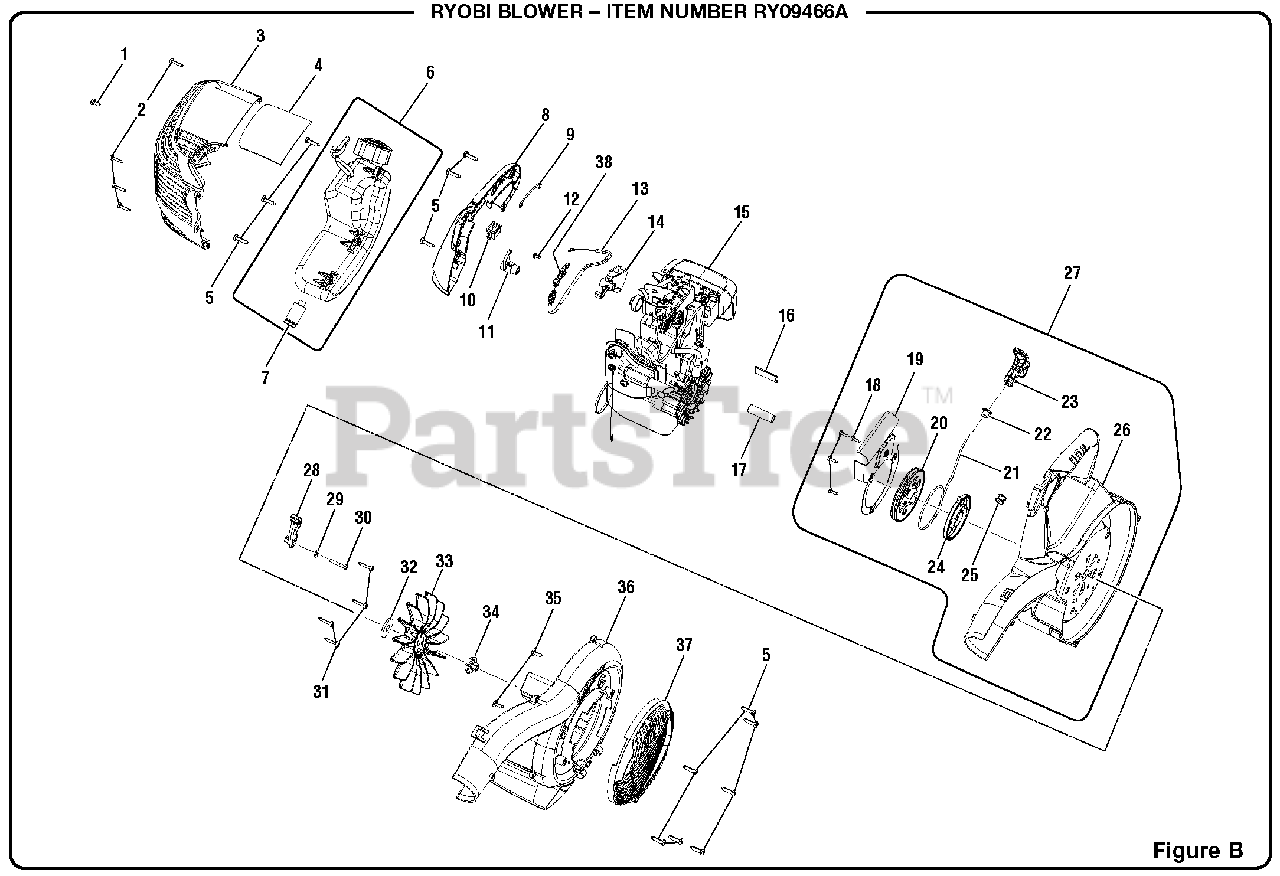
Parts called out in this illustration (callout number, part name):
1	Screw (M5 x 10.5 mm, T20 Torx Hd. )
2	Screw (M4 x 18 mm, T20 Torx Soc. Hd.)
3	Engine Housing
4	Heat Shield
5	Screw (#10-14 x 3/4 in, T25 Torx Pan Hd. T.F.)
6	Fuel Tank Assembly w/Cap
7	Fuel Filter
8	Handle Cover
9	Ground Wire
11	Trigger Lock
12	Screw (M3.5 x 7.5 mm, T20 Torx Pan Hd.)
13	Throttle Cable
15	Power Head Assembly
18	Screw (M4 x 12 mm, T20 Torx Truss Hd.)
20	Starter Pulley
21	Starter Rope
23	Starter Grip
24	Container Spring Assembly
26	Inner Volute
27	Lower Housing w/Starter
28	Cruise Lever
29	Washer (ID4.3 x OD12 x 1.5t)
30	Cruise Lever Screw (M8-14 x 25 mm, Special T20 Truss Hd.)
31	Screw (M4 x 23 mm, T20 Truss Hd. T.F.)
32	Washer (ID9.8 x OD34.27 x 2.28t)
34	Lock Nut (3/8 in.)
35	Screw (#10-14 x 1/2 in., T25 Torx Truss Hd.)
36	Outer Volute
37	Air Inlet Cover
38	Throttle Lever
